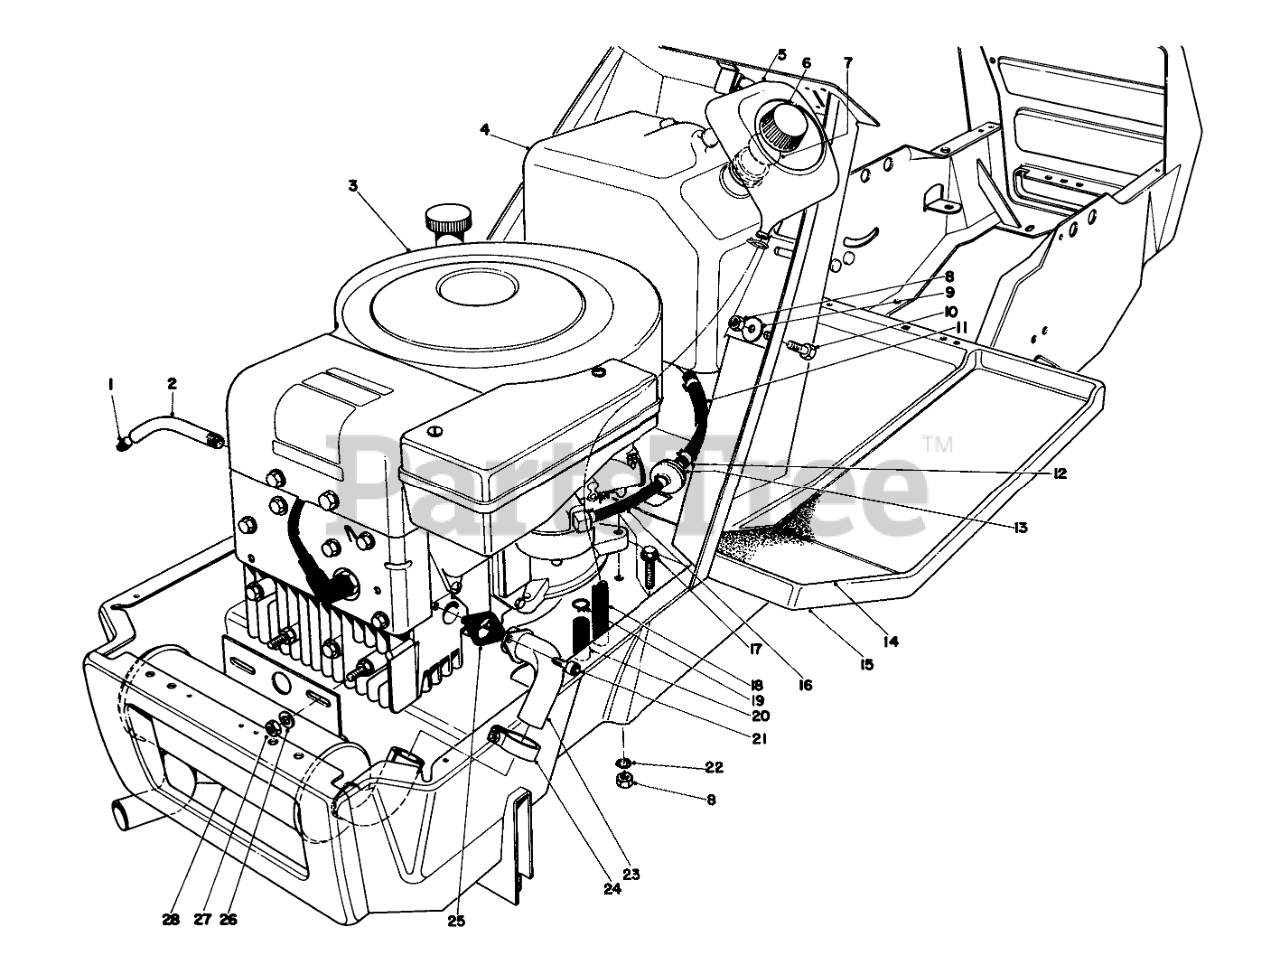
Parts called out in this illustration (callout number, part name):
1	PLUG-PIPE, SQH
2	OIL DRAIN TUBE
3	Engine
4	Gas Tank (Incl. Ref. #5)
5	Funnel-Overflow
6	Gas Cap (Incl. Ref. #7)
7	GAS CAP GASKET
8	NUT-LOCK, NI
9	WASHER
10	SCREW-HH
11	HOSE-FUEL
12	FUEL HOSE CLAMP
13	Fuel Filter
14	LH FOOT TREAD
15	Frame
16	Gas Hose
17	SCREW-HH
18	FUNNEL HOSE
19	HOSE CLAMP
20	CARB DRAIN HOSE
21	SCREW-HSH
22	WASHER-LOCK, INTERNAL
23	Exhaust Pipe
24	MUFFLER CLAMP
25	Exhaust Gasket
26	WASHER-PLAIN
27	NUT-LOCK, CONE
28	MUFFLER
